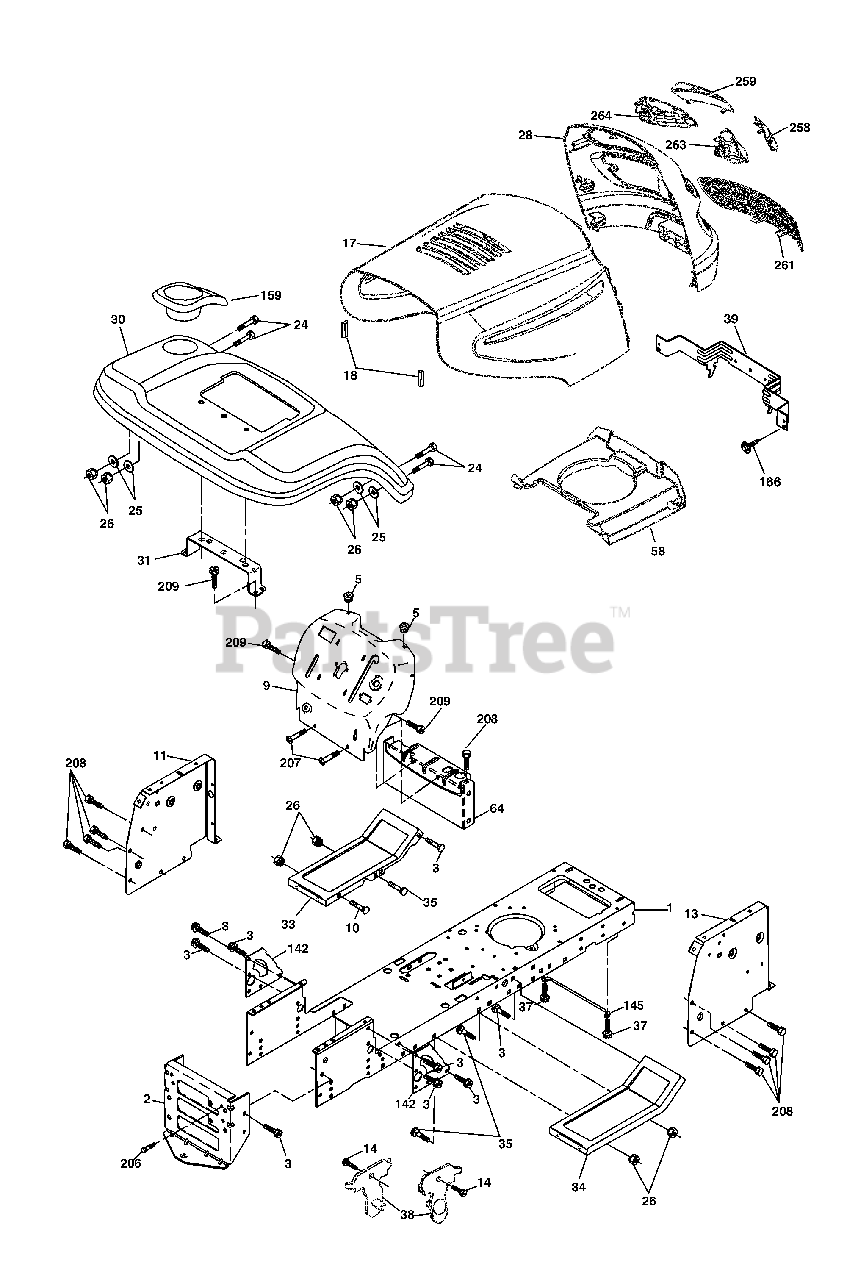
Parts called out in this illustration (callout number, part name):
1	Chassis
2	Drawbar
3	Screw 3/8-16 x 3/4
5	Bumper Hood/Dash
9	Dash
10	Bolt Rd Hd Sqnk. 3/8-16 Unc x 1
11	Panel Asm. Dash Lh
12	Clip Tinnerman Grile P/L
14	Screw Thdrol 3/8-16 x 1/2
17	Hood
18	Bumper Hood
24	Bolt Fin Hex 3/8-16 Unc x 1 Gr. 5
25	Washer 13/32 x 13/16 x 12 Ga.
26	Nut Lock Hex w/Insert 3/8-16 UNC
28	Grill/Lens Asm
30	Fender Asm
31	Bracket Fender
33	Footrest LH
34	Footrest RH
35	Bolt Rd Hd Sht. Sqnk. 3/8-16 x 3/4
37	Screw Thdrol 5/16-18 x 1/2 Tyt
38	Bracket Asm. Pivot Mower Rear
39	Bracket Pivot
58	Air Duct Private Label
64	Dash Lower
142	Plate Reinforcement
145	Rod Pivot Chassis/Hood
159	Cupholder
166	Screw #13-16 x 3/4
206	Bolt shoulder 5/16-18
207	Screw Thdrol 5/16-18 x 1/2
208	Screw Thdrol 3/8-16 x 1/2
209	Screw 3/8-16 x 3/4
258	Lens Grille RH
259	Lens Grille LH
263	Bezel Grille LH
264	Bezel Grille RH
